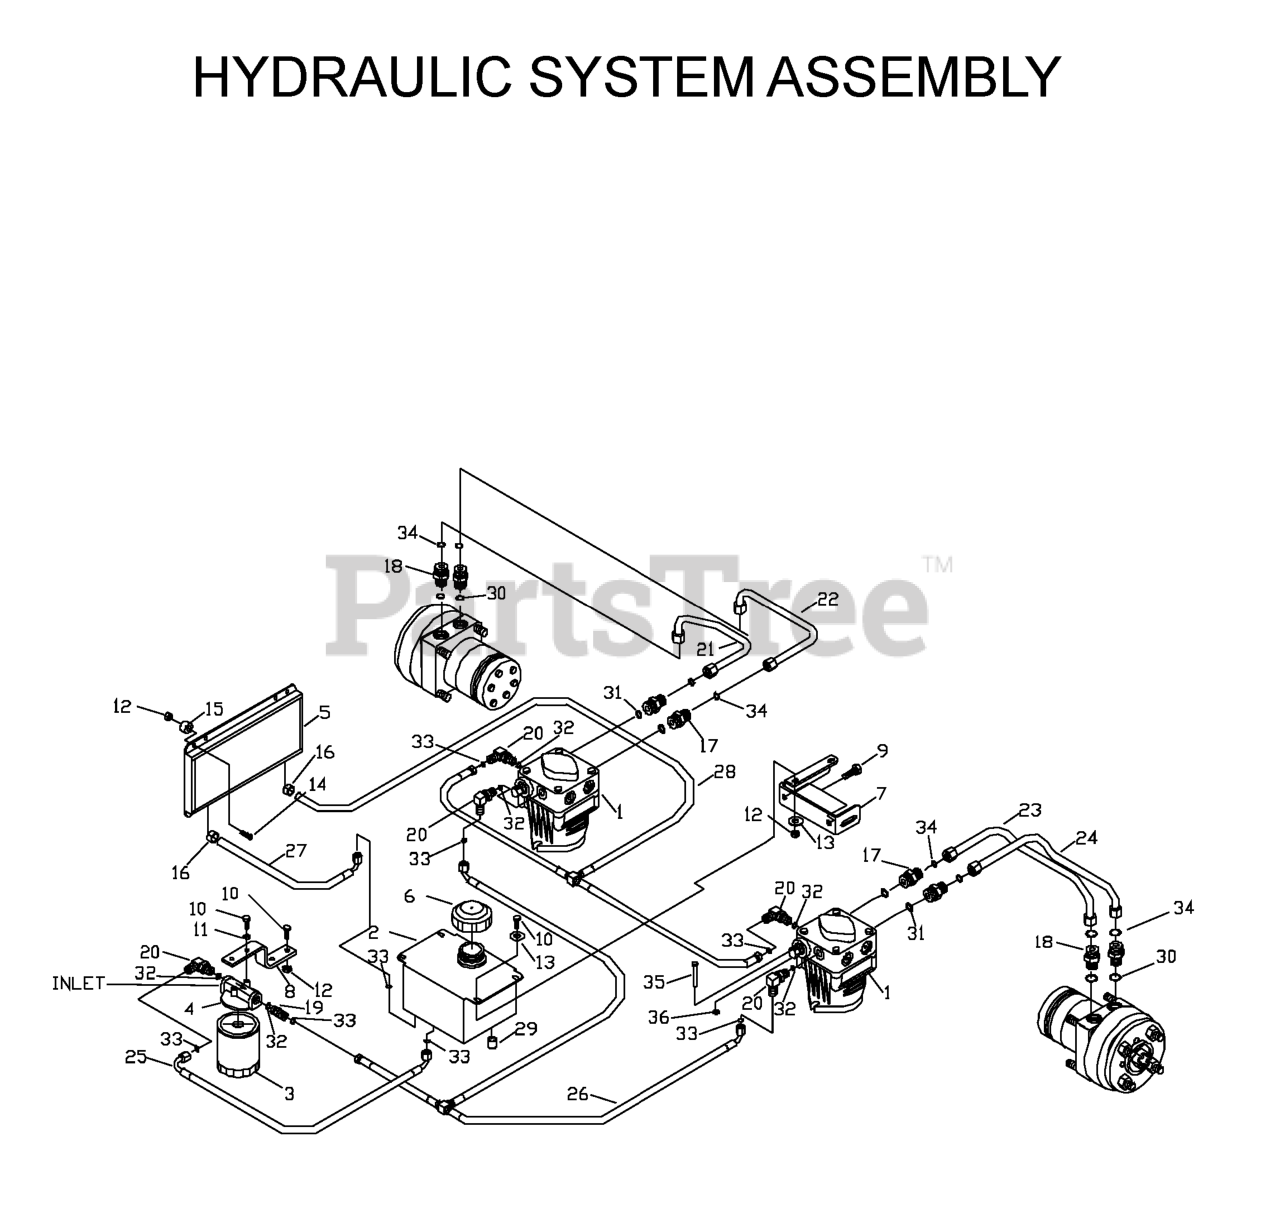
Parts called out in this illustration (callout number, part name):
1	PUMP
3	HYDRAULIC OIL FILTER
4	FILTER HEAD
6	HYDRAULIC CAP
7	TANK MOUNT LT
8	FILTER MOUNT
9	HCS 5/16C X 3/4
10	HCS 1/4C X 3/4 HCS
11	LOCKWASHER 1/4"
12	NUT 1/4C CENTERLOCK
13	WASHER 1/4 FLAT
14	HCS 1/4-20.X
16	HOSE CLAMP T-1865
17	FITTING, STRAIGHT F6400-8-8-0
19	STRAIGHT FITG
20	ELBOW, F6801-6-6-0 90 DEGREE
21	RUBBER HYDRAULIC HOSE (1)
22	RUBBER HYDRAULIC HOSE (1)
23	RUBBER HYDRAULIC HOSE (1)
24	RUBBER HYDRAULIC HOSE (1)
29	NUT 9/16-18 JIC CAP
35	CLEVIS PIN
539105026	TANK MOUNT RT
